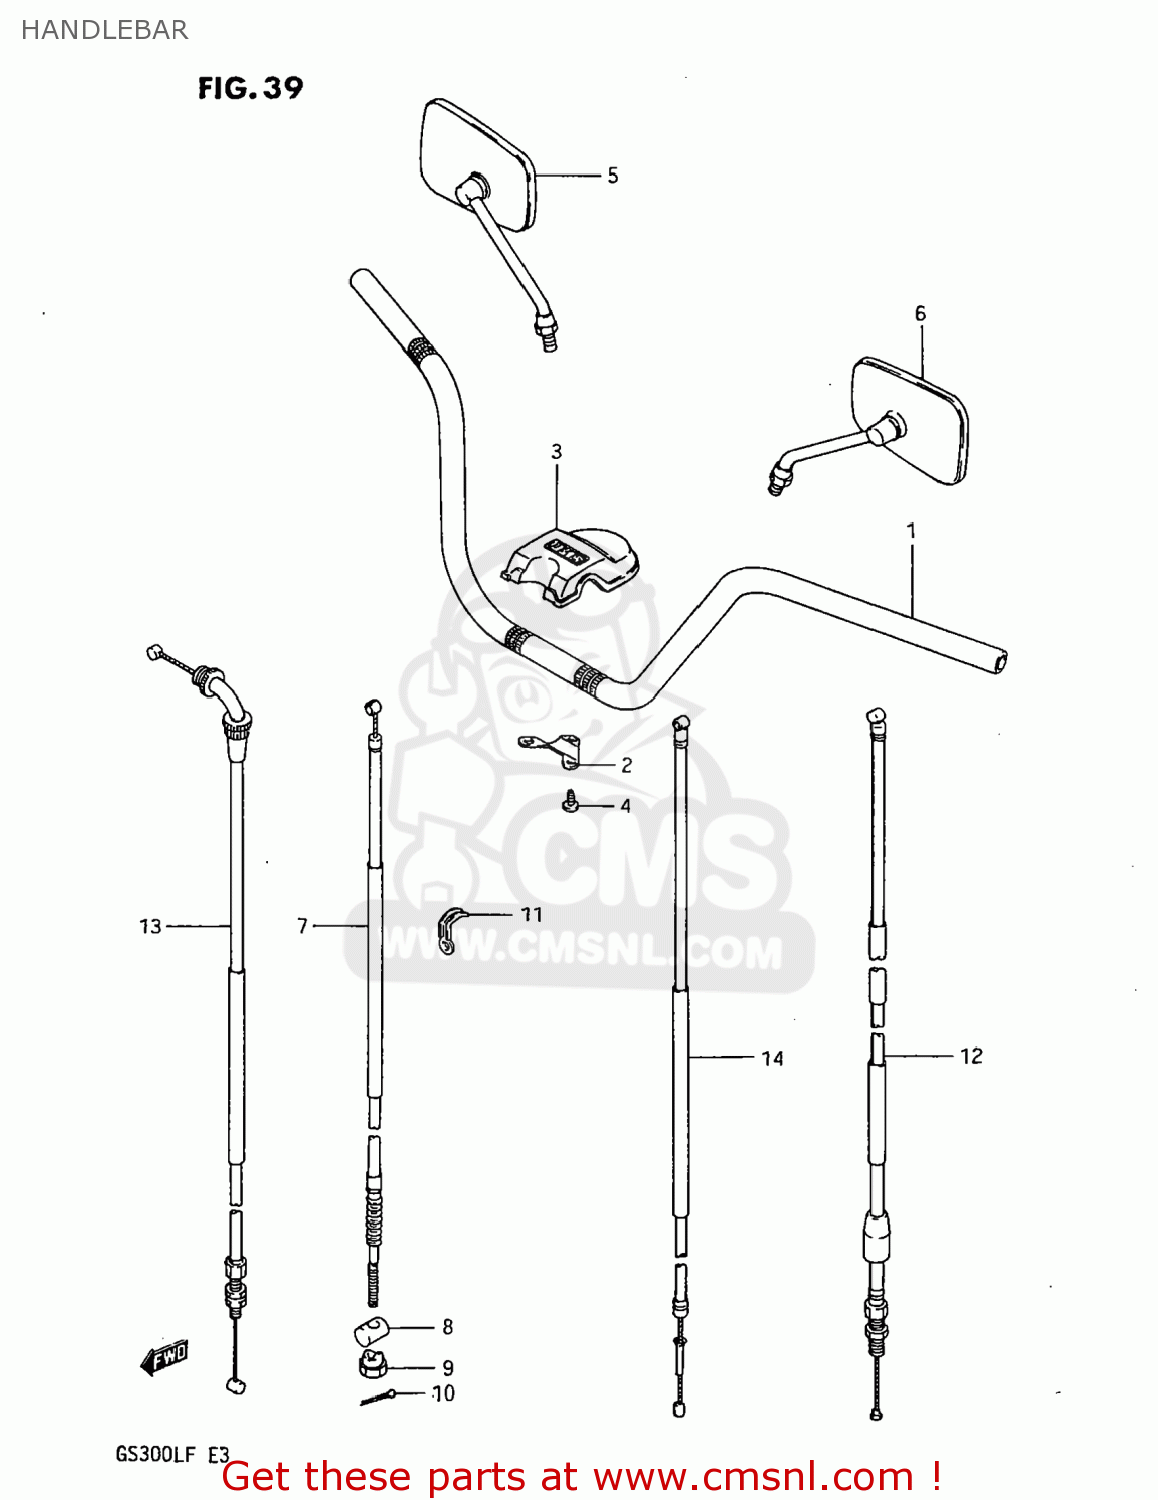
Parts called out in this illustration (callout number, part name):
1	HANDLEBAR,RIGHT
2	BRACKET,HEAD COVER
3	COVER,STEERING HEAD
4	SCREW
5	MIRROR ASSEMBLY,RIGHT
6	MIRROR ASSEMBLY,LEFT
7	CABLE ASSEMBLY,FRONT BRAKE
8	PIN
9	NUT (6MM)
10	PIN
11	LAMP ASSEMBLY
12	CABLE ASSY,CLUTCH
13	CABLE ASSEMBLY,THROTTLE
14	CABLE,STARTER
